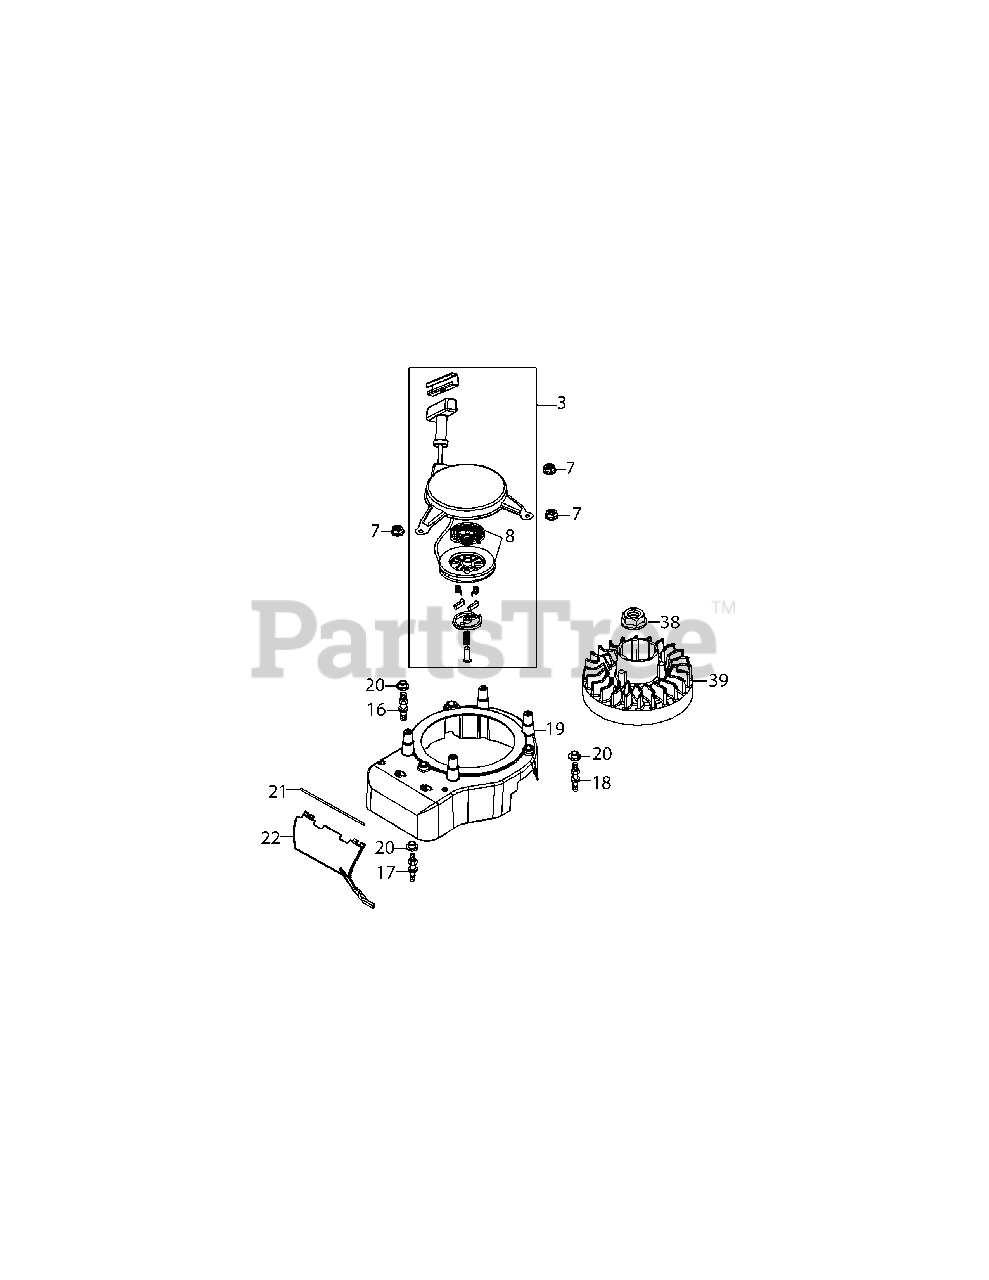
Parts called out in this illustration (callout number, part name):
3	Recoil Starter Assembly
7	Nut M6 X 10 Mm
8	Recoil Spring And Pulley Assy
16	Starter / Shroud Stud M6×85-48
17	Starter / Shroud Stud M6×87-51.5
18	Starter / Shroud Stud M6×79
19	Inner Shroud
20	Spacer
21	Air Vane Shaft
22	Air Vane
38	Flywheel Nut M14
39	Flywheel
